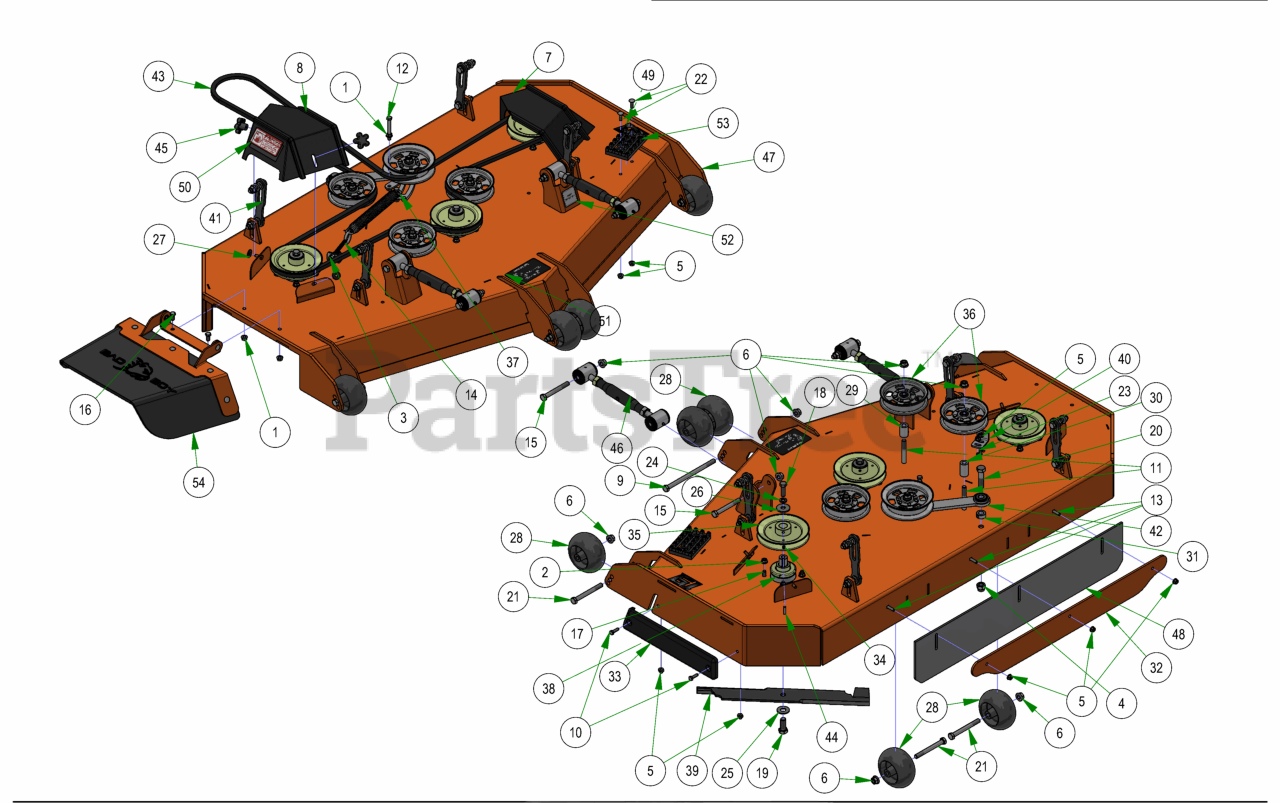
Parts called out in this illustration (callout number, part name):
1	3/8-16 HEX SERRATED FLANGE NUT HARD/ZINC
2	3/8-16 NYLON INSERT FLANGE LOCKNUT (GR.F) ZINC
3	3/8-16 HEX NUT ZINC
4	5/8-11 NYLON INSERT LOCKNUT ZINC
5	5/16-18 NYLON INSERT FLANGE LOCKNUT ZINC
6	1/2-13 NYLON INSERT FLANGE LOCKNUT ZINC
7	2019 61" Outlaw Gen2 Pulley Cover Left
8	2019 61" Outlaw Gen2 Pulley Cover Right
9	1/2-13 X 8 HEX CAP SCREW GR 5 ZINC
10	5/16-18 X 1 HEX CAP SCREW (GR.5) ZINC
11	1/2-13 X 3-1/2 HEX FLANGE BOLT (GR.8) ZINC
12	3/8-16 X 3 HEX CAP SCREW (GR.5) ZINC
13	5/16-18 X 1-1/4 CARRIAGE BOLT ZINC
14	4" 3/8-16 Eye Bolt
15	1/2-13 X 4 HEX CAP SCREW (GR.8) ZINC YELLOW
16	3/8-16 X 3/4 HEX CAP SCREW (GR.5) ZINC
17	3/8-16 X 1-1/2 HEX CAP SCREW (GR.5) ZINC
18	1/2-20 X 1-1/2 HEX CAP SCREW (GR.5) ZINC
19	5/8-18 X 1-1/2 HEX CAP SCREW (GR.8) ZINC YELLOW
20	5/8-11 X 2-1/2 HEX CAP SCREW (GR.5) ZINC
21	1/2-13 X 4-1/2 HEX CAP SCREW (GR.5) ZINC
22	5/16-18 X 1 CARRIAGE BOLT (GR.8) ZINC
23	5/16-18 X 7/8 CARRIAGE BOLT ZINC
24	1/2 SPLIT LOCKWASHER (GR.8) ZINC/YELLOW
25	5/8 USS FLAT WASHER (1-3/4" OD) GR.8 ZINC YELLOW
26	1/2 BELLEVILLE WASHER (1-5/8 OD X .140 THK) ZINC
27	.360 ID X .983 OD X .120 THICK FLAT WASHER NYLON BLACK
28	2019 Deck Wheel
29	.502 ID X .750 OD X 1.500 Long Spacer
30	1 3/4" Pulley Spacer
31	5/8 SOLID SHAFT COLLAR (W/1 SET SCREW) ZINC
32	61 Bolt in Baffle Deck v2 Stripping Plate
33	REVISED TRIM BUMPER_20180226
34	5/16-24 X 1/4 SOCKET SET SCREW (CUP PT) PLAIN
35	6 1/4" Drive Pulley
36	5-3/4 Idler Pulley
37	2019 Outlaw Gen2 Deck Spring
38	OUTLAW SPINDLE ASSEMBLY
39	61" High Lift Fusion Blade
40	2019 Deck Eye Bolt Tab
41	Deck Hanger Assembly
42	2019 Renegade Deck Idler
43	Deck Belt for 61" Renegade
44	1/4 X 1 SQ MACHINERY KEY 1018 STL PLN
45	5/16" Knob
46	Turnbuckle Assembly (M20-2.5)
47	2019 Sloped 61" Deck
48	R Series Rubber For Deck
49	61" Deck Decal
50	Danger Decal-Spindle/Discharge
51	2019 Renegade Deck Belt Route Decal
52	Deck Impact Patent Decal 9591803
53	Deck Step Assembly
54	2019 Outlaw Gen2 Chute Assembly
